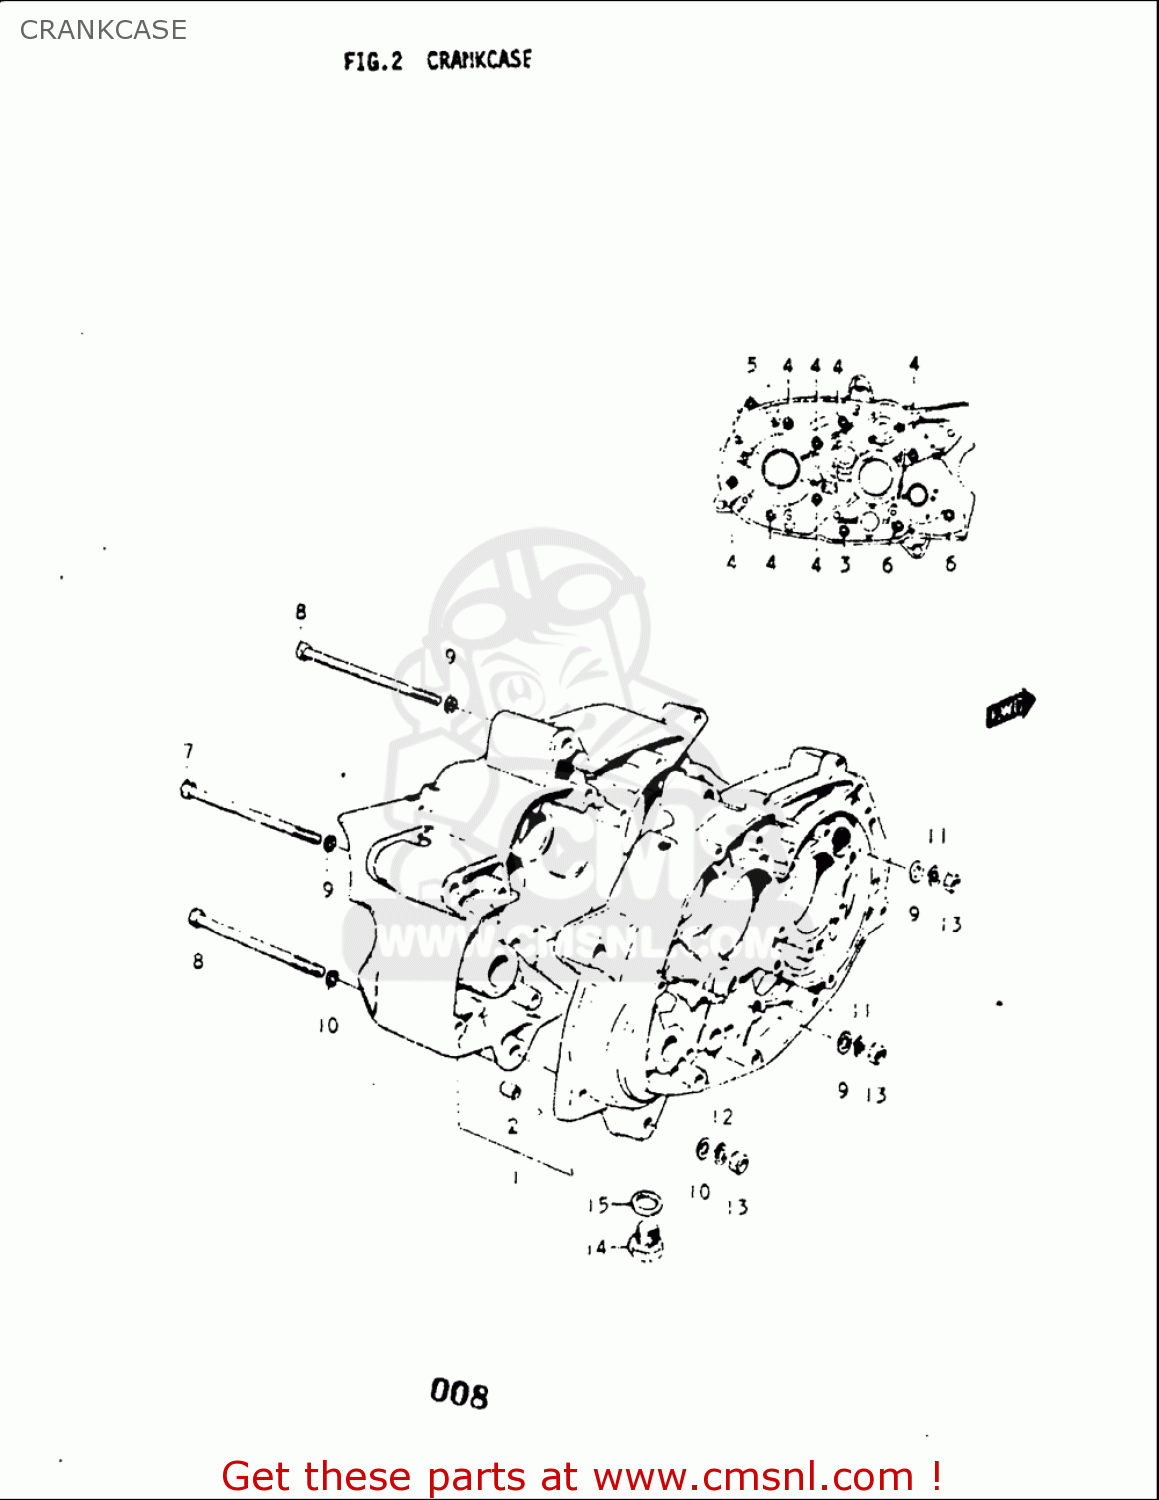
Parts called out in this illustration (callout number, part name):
2	PIN
3	SCREW
4	SCREW
5	SCREW
6	SCREW
7	BOLT(8X105)
9	WASHER
11	WASHER,LOCK
12	WASHER,LOCK
13	NUT
14	PLUG
15	GASKET(10X14X3.6) (NAS)
